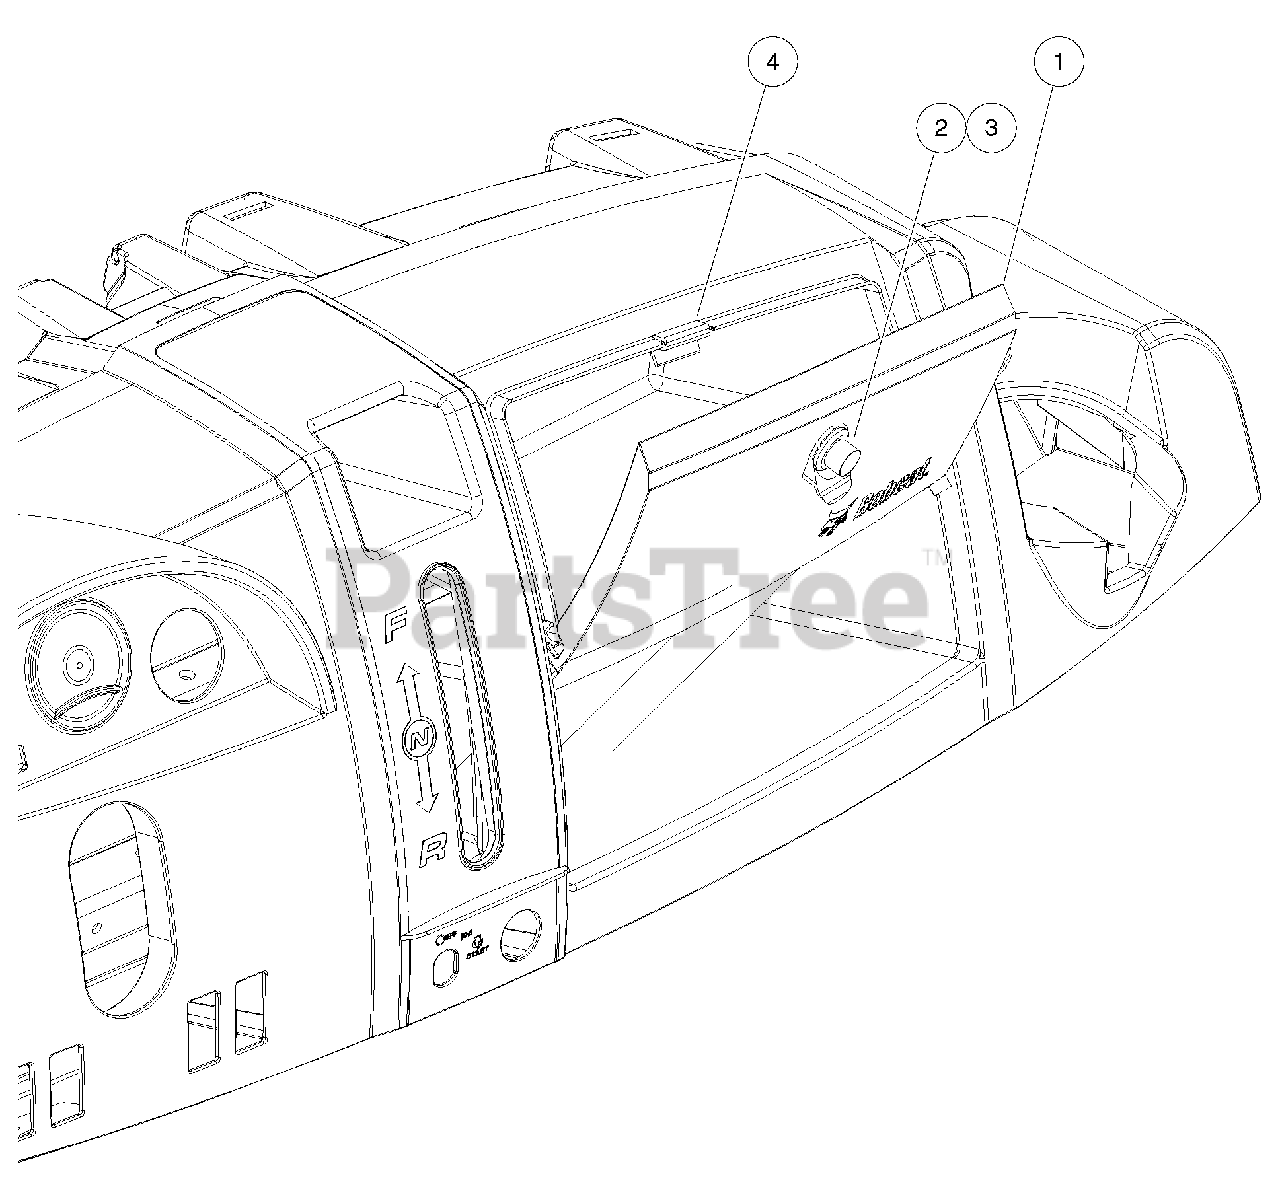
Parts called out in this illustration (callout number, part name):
1	Cover, Storage, Dash, Awd, Cci
2	Latch, Push Close
3	Latch, Push Close W/ Key
4	Keeper, Latch, Push Close
